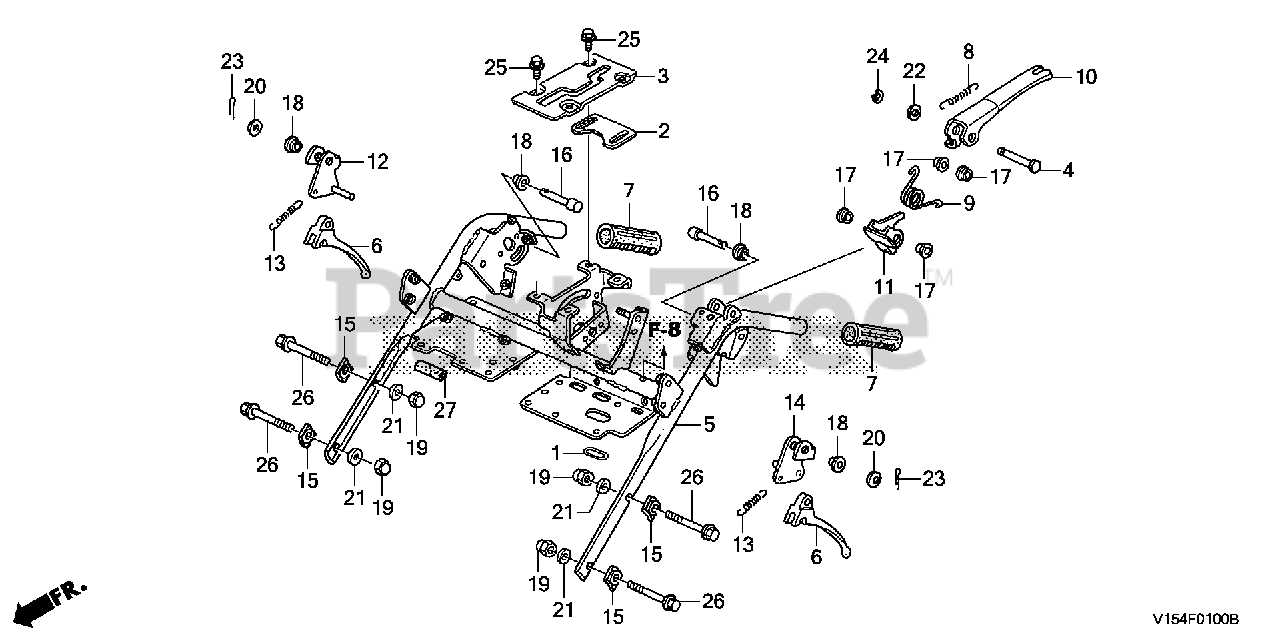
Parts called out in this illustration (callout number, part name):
2	PLATE, CHANGE ADJUSTER
3	GUIDE, CHANGE LEVER
4	PIN, KICK STARTER
5	PIPE, HANDLE (COO)
6	LEVER, R. HANDLEBAR (USED FOR BOTH SIDE) (NOT AVAILABLE)
7	GRIP, HANDLE
8	SPRING, CLUTCH LEVER RETURN
9	SPRING, CLUTCH ARM LEVER
10	LEVER, MAIN CLUTCH
11	ARM, CLUTCH LEVER
12	ARM, R. TURN LEVER
13	SPRING, TURN LEVER RETURN
14	ARM, L. TURN LEVER
15	WASHER, HANDLE JOINT
16	PIN (6X27)
17	BUSH, CLUTCH
18	BUSH, TURN LEVER
19	NUT, CAP (8MM)
20	WASHER, PLAIN (6MM)
21	WASHER, PLAIN (8MM)
22	WASHER, PLAIN (8MM)
23	PIN, SPLIT (1.6X12)
25	BOLT, FLANGE (6X12)
26	BOLT, FLANGE (8X50)
27	PROTECTOR, PCM HARNESS
